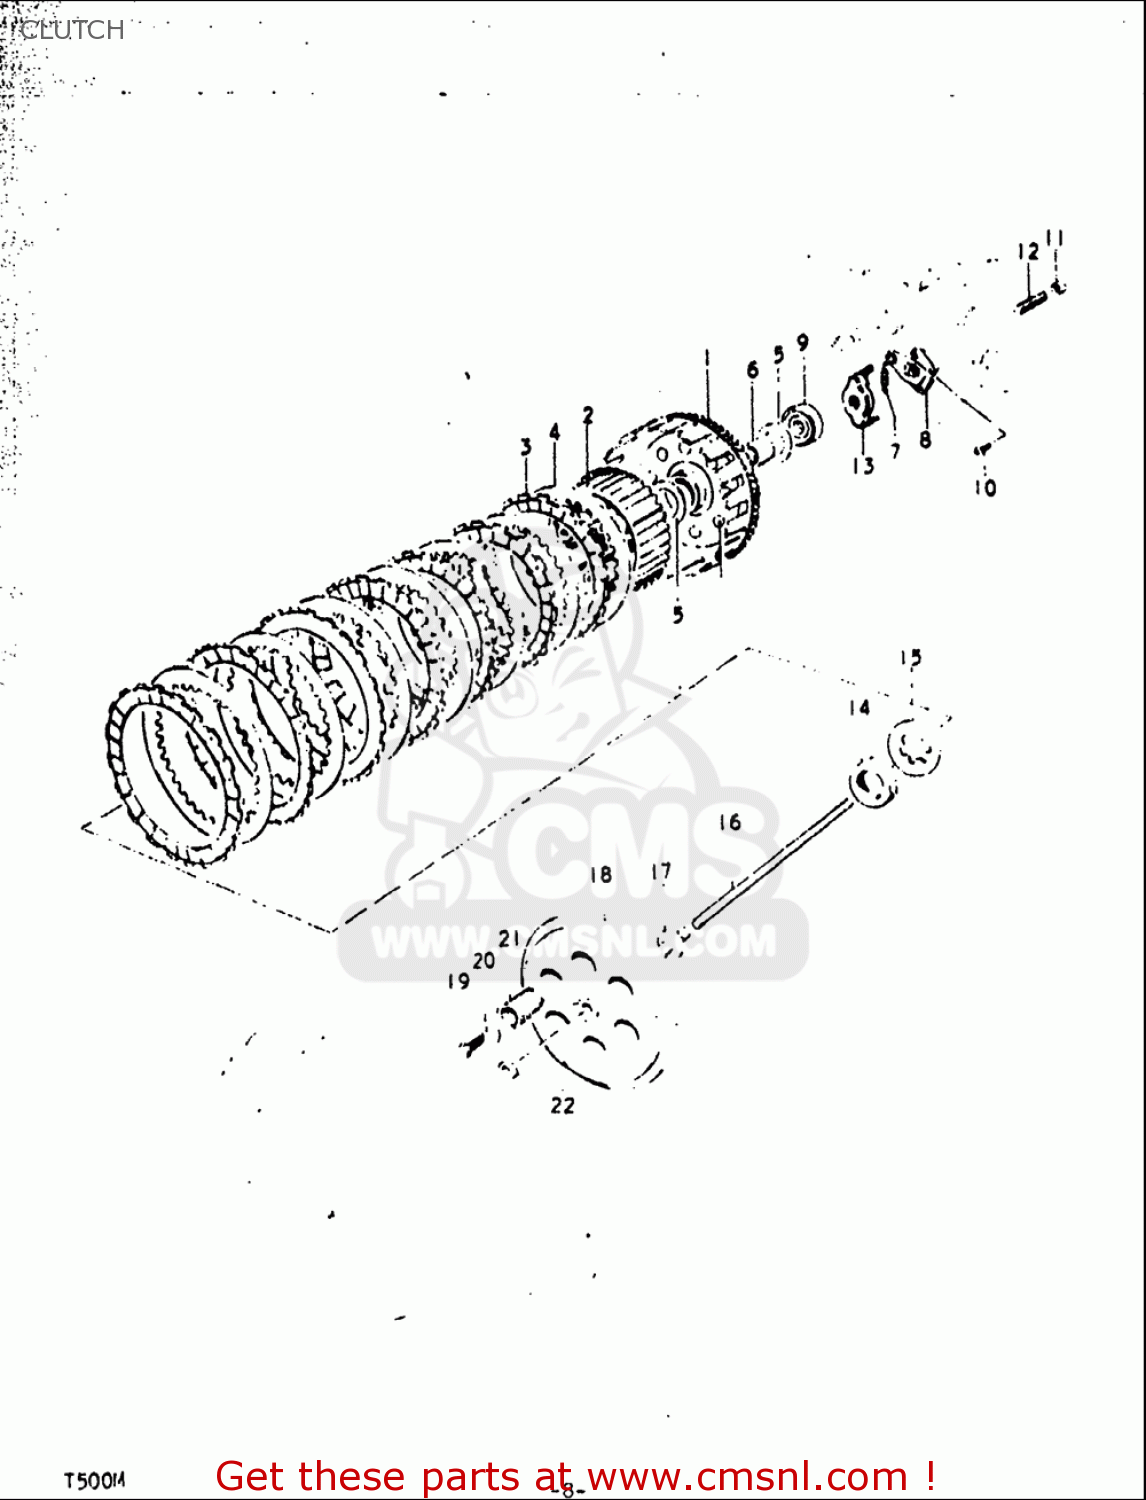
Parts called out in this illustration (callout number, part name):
1	GEAR ASSEMBLY,PRIMARY DRIVE
2	HUB,CLUTCH SLEEVE
3	PLATE,CLUTCH DRIVE (MCA)
4	PLATE,CLUTCH DRIVEN (NAS)
5	WASHER
6	SPACER
7	SPRING
8	SCREW ASSEMBLY,CLUTCH RELEASE
9	SEAL,OIL(8X32X6.5)
10	SCREW 6X12
11	NUT
12	SCREW
13	PLATE,CLUTCH RELEASE
14	NUT
15	WASHER,LOCK
16	ROD,CLUTCH PUSH
17	ROD,CLUTCH RELEASE
18	DISC,CLUTCH PRESSURE
19	BOLT
20	1
21	SPRING
22	SEAL,OIL (10X17X5)
